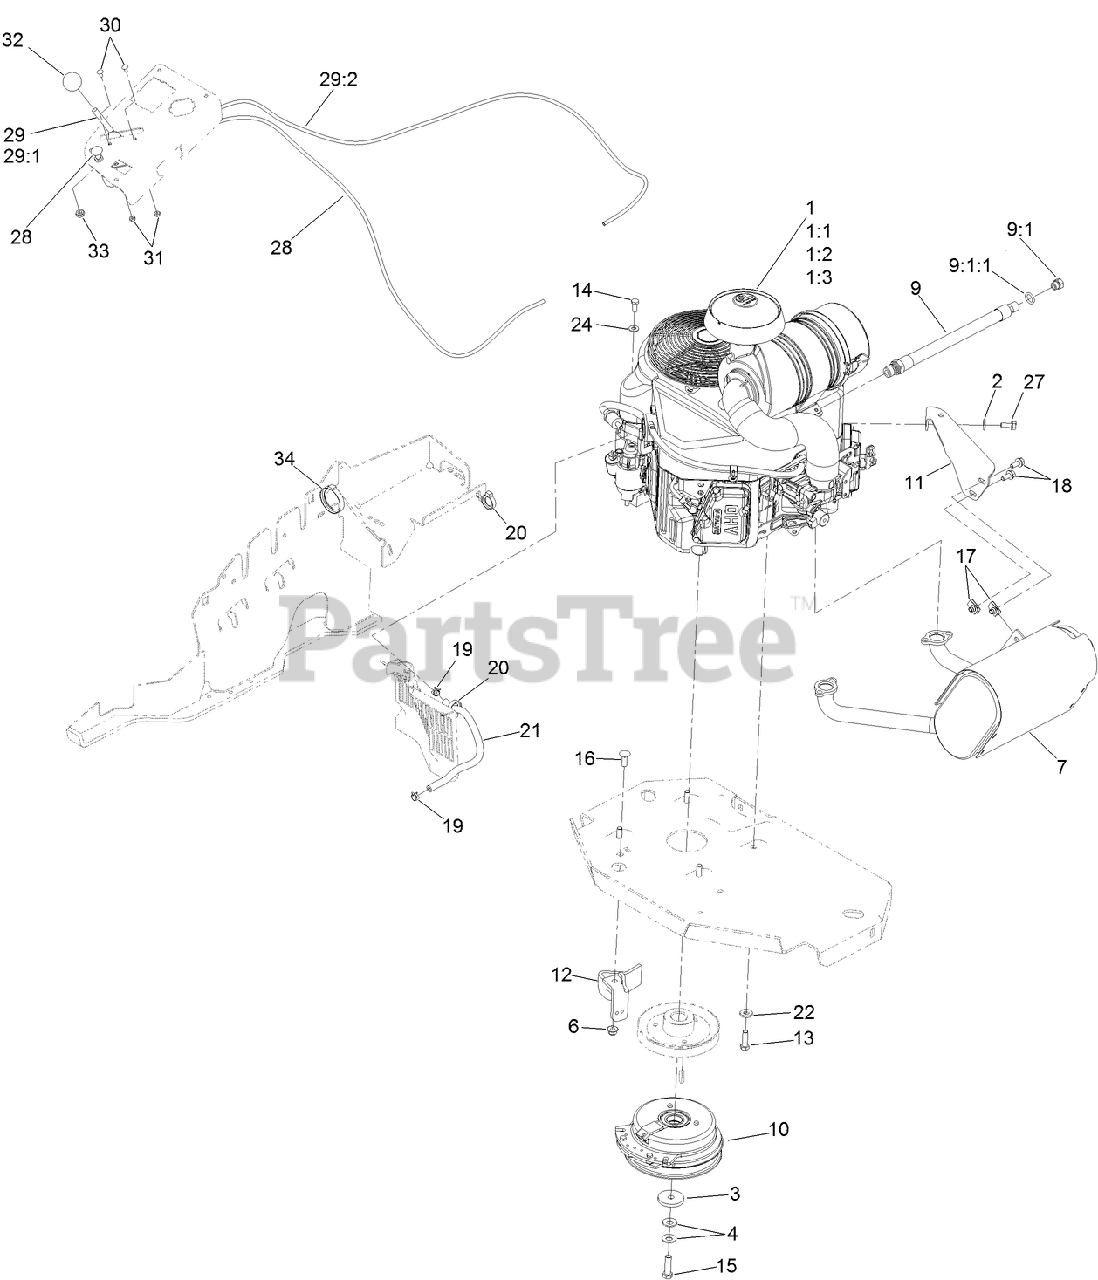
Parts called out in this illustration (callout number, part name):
1:1	KAWASAKI 49065-7007 ENGINE OIL FILTER
1:2	KAWASAKI 11013-7044 ENGINE AIR FILTER
1:3	KAWASAKI 11013-7045 SAFETY FILTER
2	WASHER-SPRING
3	WASHER-CLUTCH
4	WASHER-SPRING
6	NUT-HF, NI
7	MUFFLER
9	ENGINE OIL DRAIN HOSE ASM
9:1	PLUG-HH
9:1:1	O-RING
10	CLUTCH KIT
11	BRACKET-MUFFLER
12	CLUTCH-ANCHOR
13	SCREW-HH
14	SCREW-HH
15	SCREW-HH, W/LOCTITE
16	SCREW-CARR
17	NUT-U
18	SCREW-HH
19	CLAMP-HOSE
20	CLAMP-HOSE
21	HOSE-FUEL
22	WASHER-BELLEVILLE
24	WASHER-PLAIN
27	SCREW-HHF
28	CONTROL-CHOKE
29	THROTTLE CONTROL ASM
29:1	LEVER-THROTTLE
30	BOLT-CARR
31	NUT-LOCK, NI
32	KNOB-BALL
33	NUT-HJ
34	CLAMP-HARNESS
